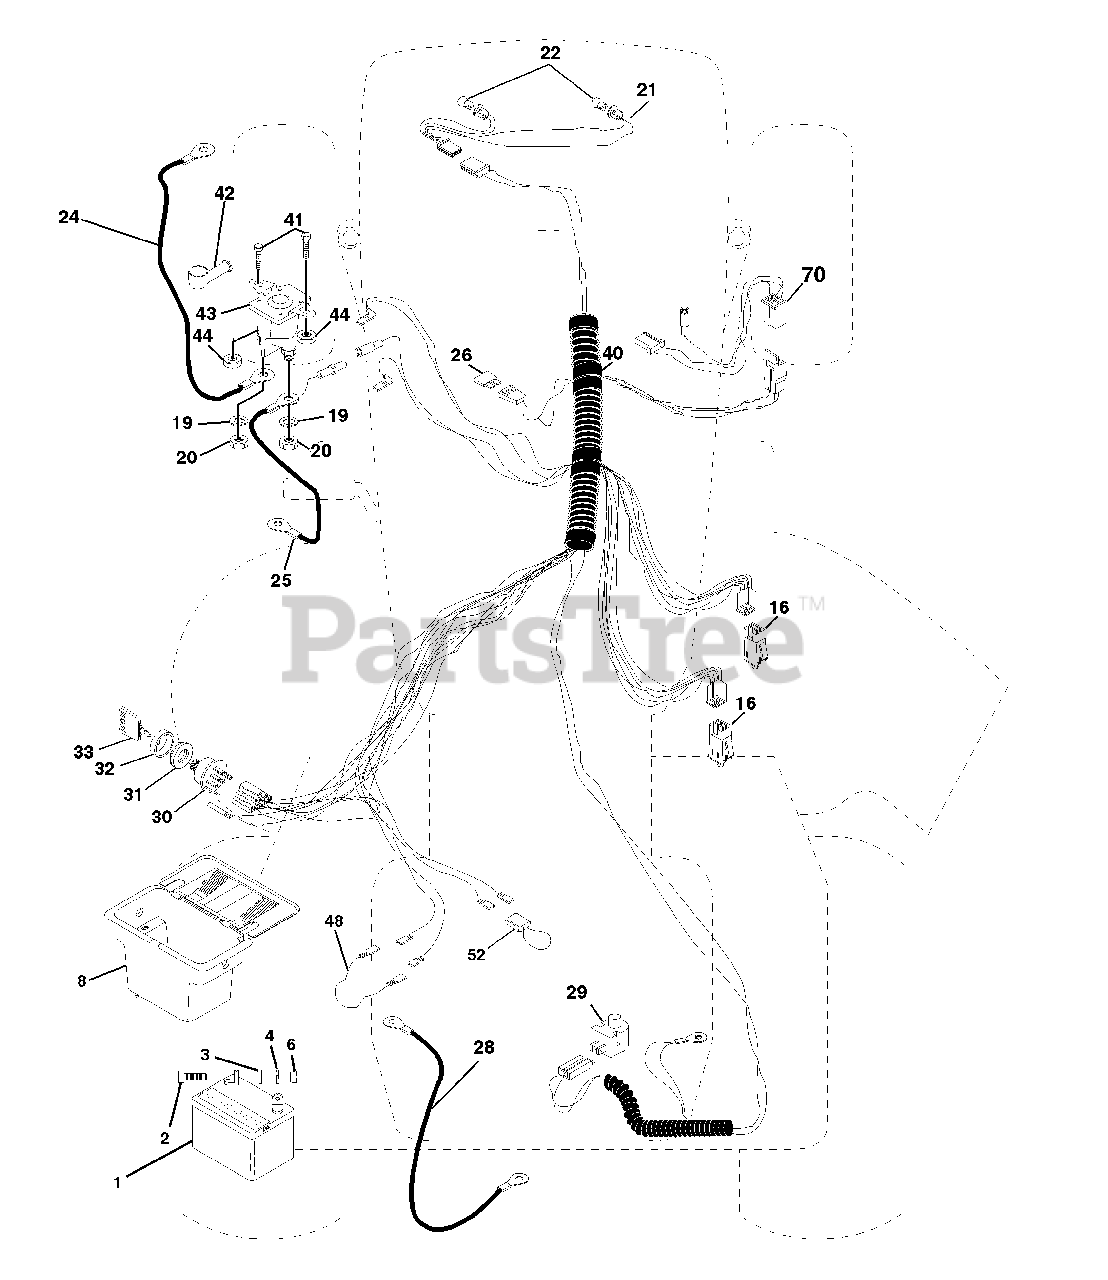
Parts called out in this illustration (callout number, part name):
1	Battery 12 Volt 25 AMP
2	Bolt Hex Hd 1/4-20unc X 3/4
3	Washer 9/32 X 5/8 X 16 Ga.
4	Washer Lock Hvy Helical 1/4
6	Nut Fin Hex 1/4-20 Unc
8	Case Battery Mech Hinge
16	Switch Interlock Push-In
19	Washer Lock 1/4
20	Nut Jam Hex 1/4-20 Unc
21	Harness Asm Light W/4152j
22	Bulb Light #1156
24	Cable Battery 6 Ga 11" red
25	Cable Battery 6 Ga 44" red w/16 wire
26	Fuse 30 AMP Auto Green
28	Cable Ground 6 Ga 12" black
29	Switch Plunger Nc Gray
30	Switch Ign 4 pos w/lights
31	Nut Ignition
32	Cover Sw Ignition
33	Key Ign Modelled Generic
40	Harness Ign.
41	Bolt Blk Fin Hex 1/4 - 20 x 1/2
42	Cover Terminal Red
43	Solenoid
44	Nut Keps Hex 1/4-20 Unc
48	Adapter Ammeter Rectangular
52	Protection Wire Loop
70	Harness, Eng. B&S Dual
